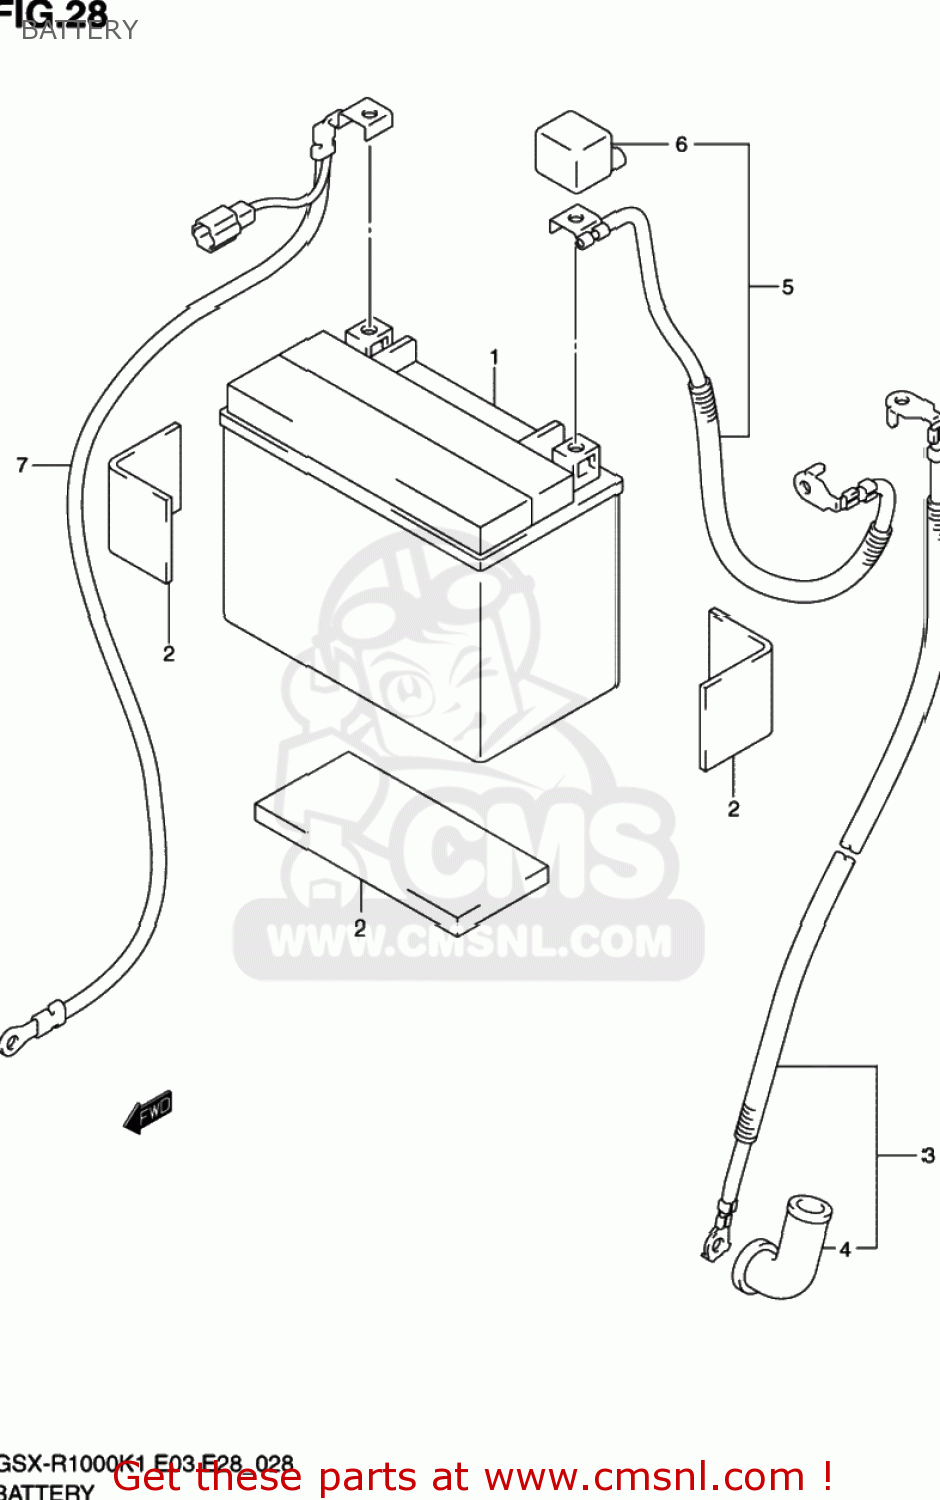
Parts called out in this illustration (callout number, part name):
1	BATTERY ASSEMBLY (12V) FTX
2	PROTECTOR(170X95X3.0)
3	WIRE,STARTER
4	CAP,STARTER MOTOR LEAD
5	WIRE,BATTERY PLUS LEAD
6	CAP,BATTERY PLUS
7	WIRE,BATTERY MINUS LEAD
